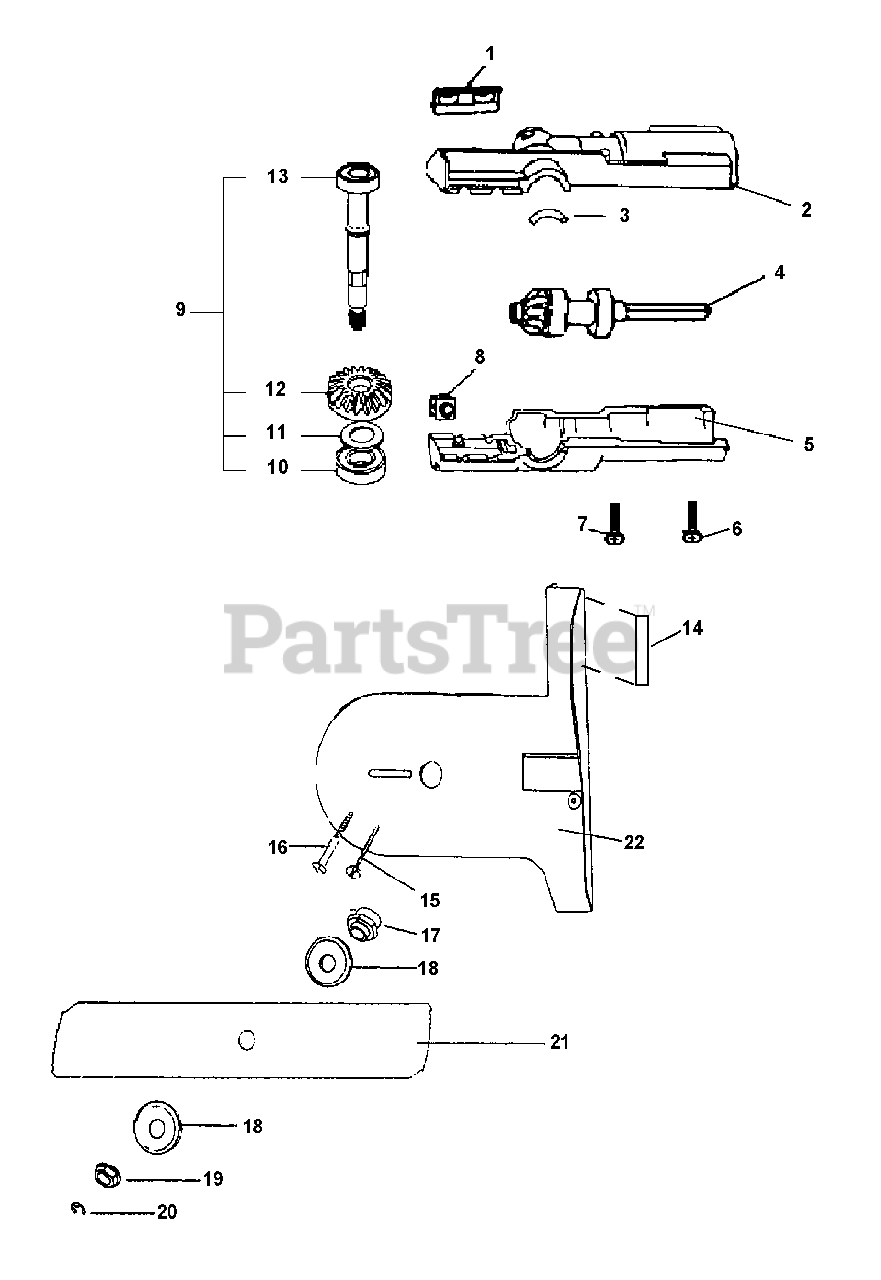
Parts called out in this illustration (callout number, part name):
1	BRACKET, GUIDE BAR
2	CASE, GEAR
4	SHAFT GEAR ASSY
5	CASE, GEAR
6	SCREW - 10-24 X 1-1/4"
8	SPACER
9	SHAFT GEAR ASSY
10	BEARING, BALL - 6001 DDU
12	GEAR - BEVEL
13	SHAFT GEAR ASSY
14	LABEL - CAUTION
15	SCREW
17	MOUNT, BLADE
18	SAW COLLAR
19	NUT - FLANGE
20	RING, RETAINING
21	BLADE, HEDGER
22	SHIELD, DEBRIS
